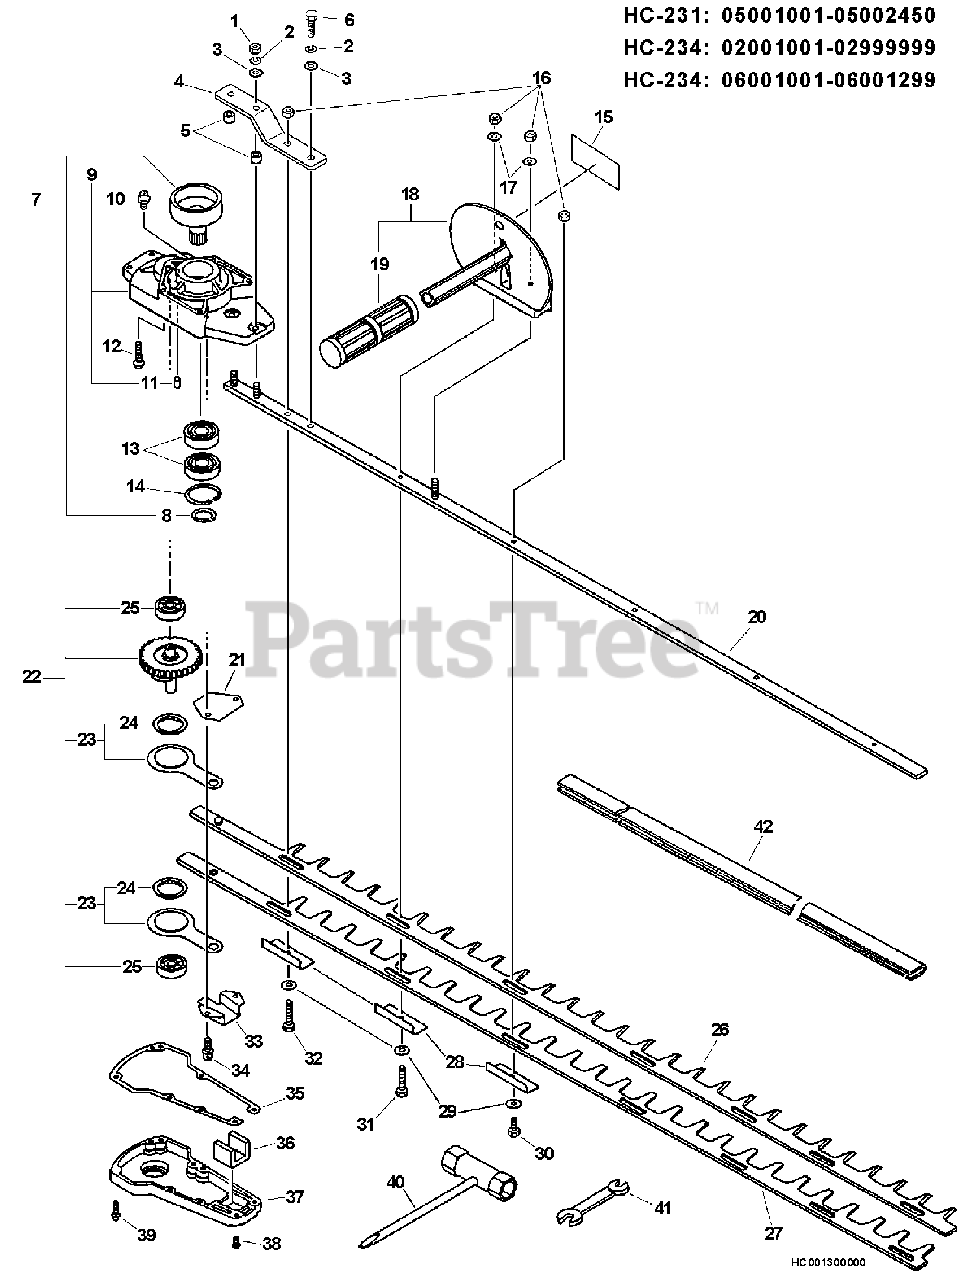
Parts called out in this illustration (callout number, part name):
1	LOCKNUT - 6
2	LOCKWASHER - 6
3	WASHER - 6
4	BRACKET, ANGLE
6	BOLT - 6X10
7	DRUM, CLUTCH
8	RING, RETAINING - 16
9	CASE, GEAR
10	FITTING, GREASE
11	PIN - LOCATING
12	SCREW - 5X30
13	BEARING, BALL - 6003
14	RING, RETAINING - 35
15	LABEL - CAUTION
16	LOCKNUT - 6
17	WASHER - 6
18	HANDLE ASSY - FRONT
19	GRIP, HANDLE
20	SUPPORT, BLADE
21	PLATE, GUIDE
22	GEAR ASSY
23	CONNECTING ROD ASSY
24	BEARING, NEEDLE
25	BEARING, BALL - 6200
26	BLADE - 40" (101cm) -- LOWER
27	BLADE - 40" (101cm) -- LOWER
28	INSULATOR
32	BOLT - 6
33	GUIDE, BLADE
34	SCREW - 4X16
35	GASKET, GEAR CASE
36	SEAL, FELT
37	LID, GEAR CASE
38	SCREW - 4X14
39	SCREW - 4X22
40	T-WRENCH - 13X19mm
41	SPANNER - 8X10mm
42	COVER, BLADE
